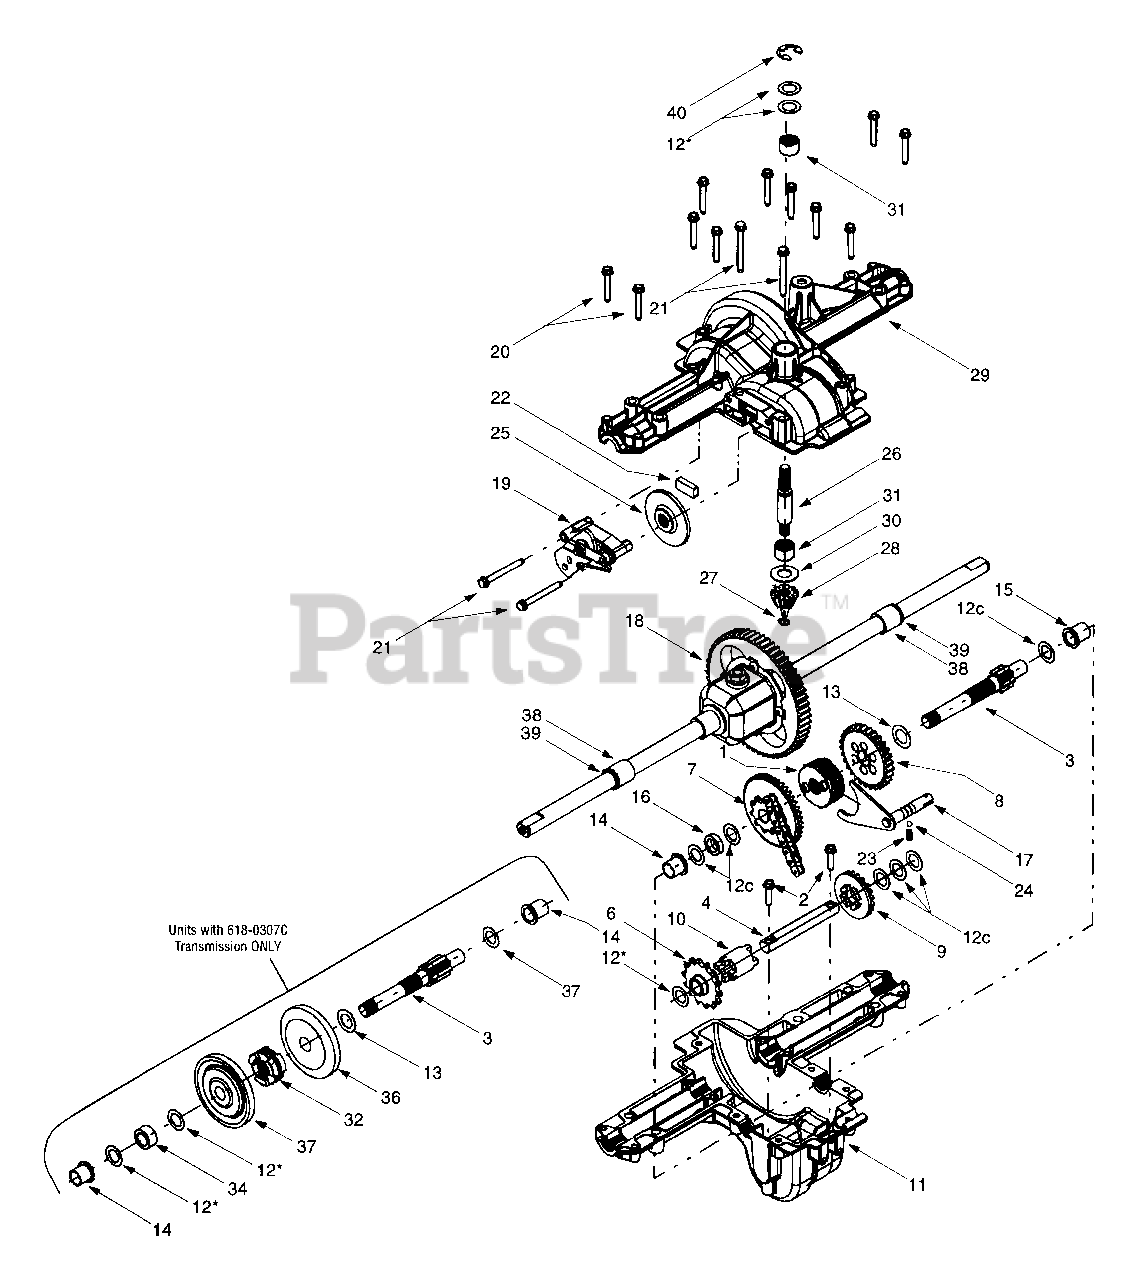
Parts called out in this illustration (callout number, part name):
1	Clutch Collar
2	Self-tapping Screw, 1/4-20 x 1.0
3	Drive Shaft
4	Counter Shaft
6	14-tooth Sprocket
7	Sprocket Bevel Gear, 42/10
8	29-tooth Spur Gear
9	20-tooth Spur Gear
10	Counter Shaft Coupling
11	Lower Housing
12C	Flat Washer, 5/8 x 1.0 x .020
13	Flat Washer, .70 x 1.125 x .031
14	Flange Bearing, 5/8 x 3/4 x 3/4
15	Flange Bearing, 5/8 x 3/4 x 15/16
16	Spacer, .635 x 1.0 x .27
17	Detent Shaft Assembly
18	Differential Assembly
19	Brake Assembly
20	Self-tapping Screw, 1/4-20 x 1.625
21	Self-tapping Screw, 1/4-20 x 2.375
22	Brake Pad
23	Compression Spring
24	Detent Ball
25	Brake Disc
26	Input Shaft
27	Retaining Ring, .394
28	12-tooth Bevel Pinion
29	Upper Housing
30	Thrust Washer, .63 x 1.24 x.062
31	Needle Bearing, .625 x .875
32	Clutch Collar
34	Spacer, .633 x 1.0 x .513
36	42-tooth Bevel Gear
37	Thrust Washer, 1.0 x .632 x .0
38	Sleeve Bearing, .75 x .1.0 x 1.0
39	Seal, .75 x 1.0 x .125
40	E-ring, .75
